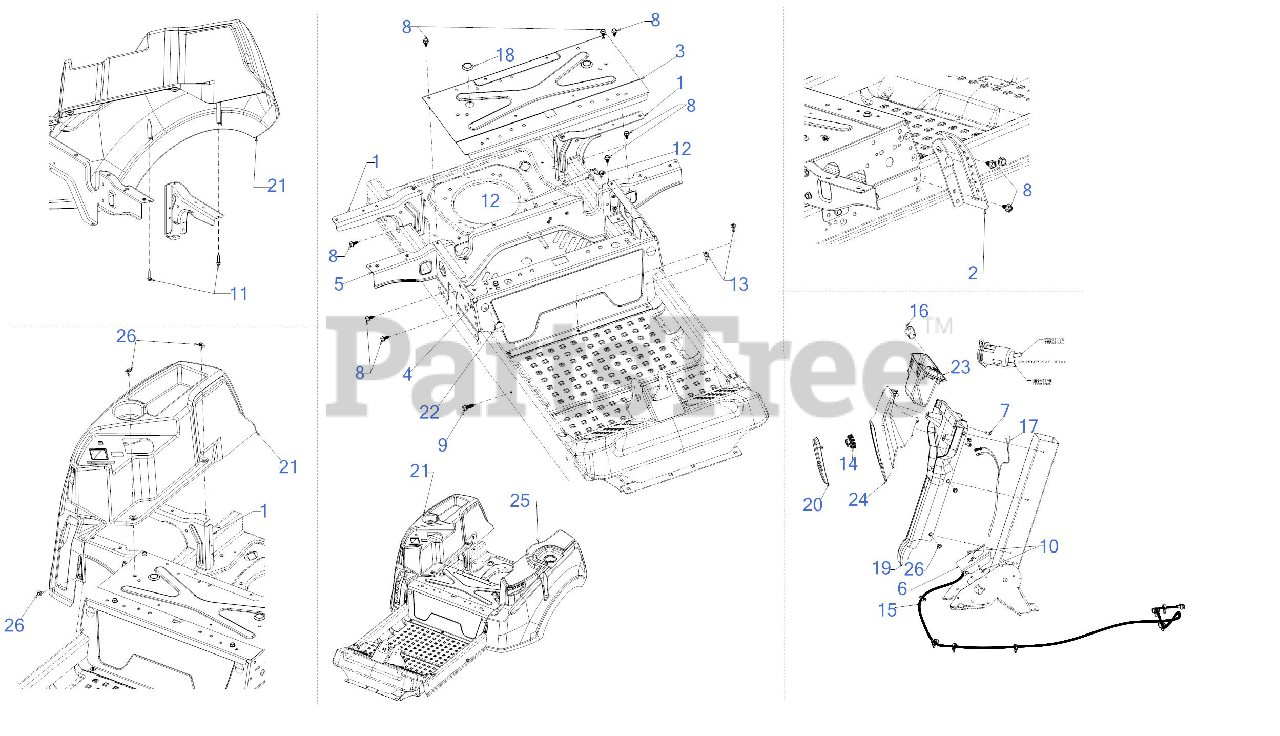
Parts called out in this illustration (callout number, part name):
2	HEIGHT INDEX BRACKET
7	SCREW 1/4-10:.625
8	SCREW 5/16-18 x .750
9	SCREW 3/8-16 x 1
10	SCREW 1/4-20 x .5
11	SCREW 5/16-14 x 1
12	SCREW 5/16-18 x .500
13	SCREW 5/16-18 X.75
14	HEADLIGHT ASSEMBLY
14	LED HEADLIGHT SOCKET (150 LUMNES)
15	HEADLIGHT JUMPER HARNESS
16	12V POWER RECEPTICAL
17	HEADLIGHT/CHARGE PORT HARNESS
19	STEERING COLUMN COVER
20	LED HEADLIGHT LENS
21	CONSOLE (RH)
22	PLASTIC PLUG
23	STEERING COLUMN STORAGE BIN
24	STEERING COLUMN/HEADLIGHT COVER
25	CONSOLE (LH)
26	SHOULDER SCREW M6-1 .368 X.115
